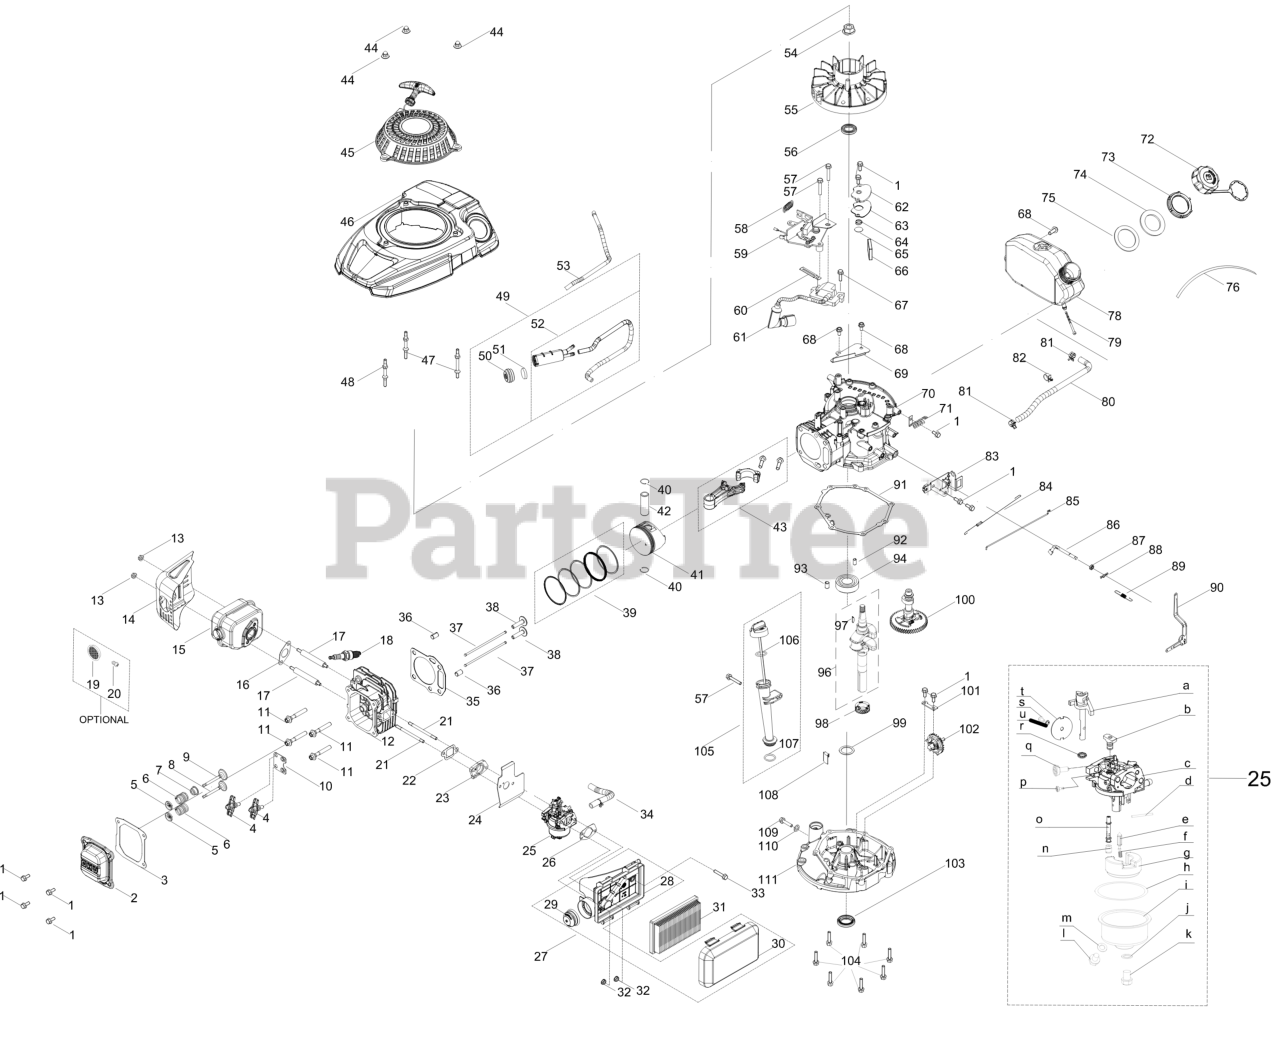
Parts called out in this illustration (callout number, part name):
1	BOLT M6-1 x 14 GR8.8
2	VALVE COVER
3	VALVE COVER GASKET
4	ROCKER ARM ASSEMBLY
5	VALVE SPRING RETAINER
6	VALVE SPRING
7	INTAKE VALVE SEAL
8	EXHAUST VALVE
9	INTAKE VALVE
10	PUSH ROD GUIDE
11	BOLT-M8 x 54
12	CYLINDER HEAD
14	MUFFLER SHIELD
16	MUFFLER GASKET
17	STUD M6-1 x 95
18	SPARK PLUG
19	SPARK ARRESTOR
20	SCREW M3.5 x 9.5
21	CARBURETOR STUD-M6 x 87
22	CARBURETOR GASKET
23	CARBURETOR INSULATOR
24	CARBURETOR GASKET
25	CARBURETOR ASSEMBLY HY-1X65BA
26	AIR FILTER BASE GASKET
27	AIR FILTER ASSEMBLY
28	AIR FILTER BASE
29	PRIMER BULB (NON-VENTED)
30	AIR FILTER COVER
31	AIR FILTER
33	BOLT-M6-1 x 30 GR8.8
34	BREATHER HOSE
35	CYLINDER HEAD GASKET
37	PUSH ROD
38	TAPPET
39	PISTON RING SET
40	SNAP RING-PISTON PIN
41	PISTON
42	PISTON PIN
43	CONNECTING ROD ASSEMBLY
44	ACORN NUT
45	RECOIL STARTER ASSEMBLY
46	BLOWER HOUSING
47	STARTER/SHROUD REAR STUD
48	STARTER/SHROUD FRONT STUD
49	CARBON CANISTER
50	CARBON CANISTER FILTER CAP
51	CARBON CANISTER FILTER
52	CARBON CANISTER
53	CARBON CANISTER PURGE HOSE
54	FLYWHEEL NUT
55	FLYWHEEL
56	CRANKSHAFT SEAL
57	BOLT M6-1 x 35 GR8.8
58	ENGINE BRAKE SPRING
59	ENGINE BRAKE ASSEMBLY
60	FLEXIBLE CLAMP
61	IGNITION COIL
62	BREATHER COVER PLATE
63	BREATHER GASKET
64	BREATHER VALVE SPRING
65	BREATHER VALVE
66	BREATHER SCREEN
67	BOLT M6-1 x 20 GR8.8
68	BOLT M6-1 x 12 GR8.8
69	AIR VANE COVER PLATE
71	FLEXIBLE CLAMP
72	FUEL CAP ASSEMBLY
73	FUEL TANK NUT
74	FUEL TANK UPPER GROMMET
75	FUEL TANK LOWER GROMMET
76	CABLE TIE - 3 x 150
79	FUEL FILTER
81	HOSE CLAMP
82	FUEL LINE SUPPORT CLAMP
83	COMPONENT BRACKET
84	THROTTLE LINKAGE SPRING
85	THROTTLE LINKAGE
86	GOVERNOR ARM SHAFT
87	GOVERNOR SEAL
88	COTTER PIN
89	GOVERNOR SPRING
90	GOVERNOR ARM ASSEMBLY
91	CRANKCASE COVER GASKET
92	DOWEL PIN
93	DOWEL PIN
96	CRANKSHAFT
97	FLYWHEEL KEY
98	CRANKSHAFT TIMING GEAR
99	THRUST WASHER
100	CAMSHAFT ASSEMBLY
101	GOVERNOR GEAR MOUNTING PLATE
102	GOVERNOR GEAR/SHAFT ASSEMBLY
103	LOWER CRANKSHAFT SEAL
104	BOLT-M6-1 x 28 GR8.8
105	OIL DIPSTICK ASSEMBLY
106	O-RING
108	OIL RETURN SEAL
109	OIL DRAIN PLUG
110	WASHER
111	CRANKCASE COVER
U	Throttle Plate Lock Washer
